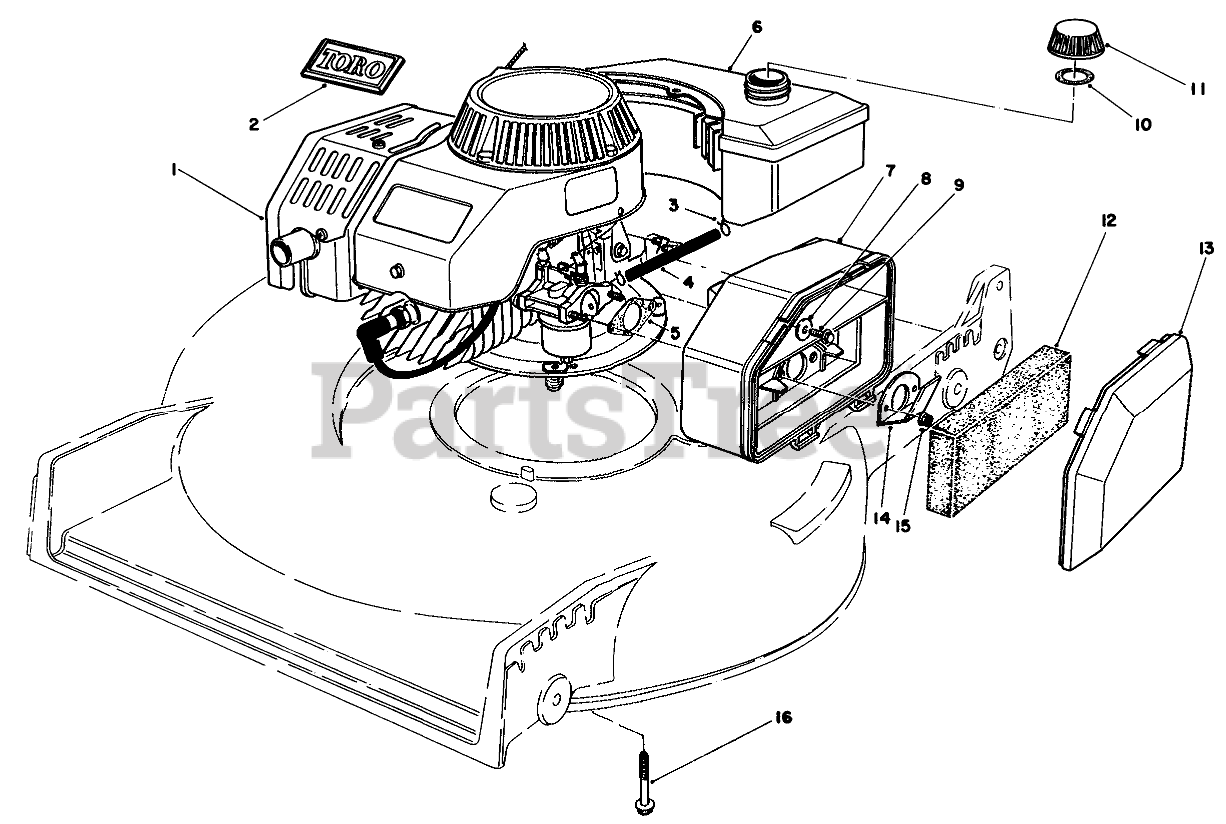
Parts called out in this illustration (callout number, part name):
1	Engine
2	TORO LOGO PLT
3	CLAMP-HOSE
4	FUEL LINE
5	GASKET-AIR CLEANER
6	Gas Tank Assembly
7	AIR CLEANER
8	WASHER-FLAT
9	SCREW-HH
10	GAS CAP GASKET
11	Gas Cap Assembly (Incl. Ref. #10)
12	FILTER
13	AIR CLEANER COVER
14	SPIT BACK DEFLECTOR
15	NUT-LOCK
16	SCREW-HHF
